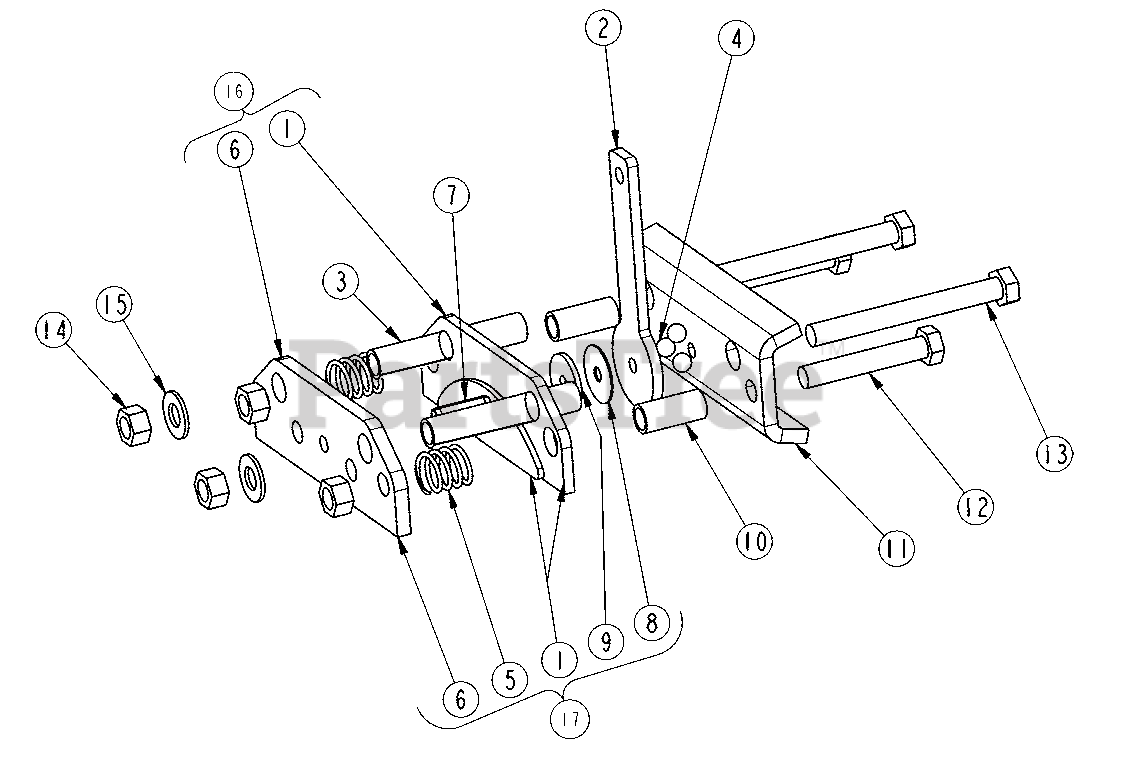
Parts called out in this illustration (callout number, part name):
1	BRAKE CALIPER STATOR ASSEMBLY
2	LEVER
3	SLEEVE
4	STEEL BALL
5	COMPRESSION SPRING
6	STATOR ASSEMBLY
7	SPRING PIN SLOTTED
8	SHIM
9	THRUST WASHER
10	SLEEVE
11	STATIONARY ACTUATOR
12	BOLT, HEX 3/8-16 X 2 1/4 GR5
13	HHCS 3/8-16 X 3 1/2 GR8 PLT
14	NUT HEX TOP LOCK 3/8-16 PLT
15	WASHER FLAT 3/8 SAE PLT
16	BRAKE PAD REPLACEMENT KIT (Includes 1 and 6)
17	CALIPER REPAIR KIT (Includes 1, 5, 6, 8 and 9)
